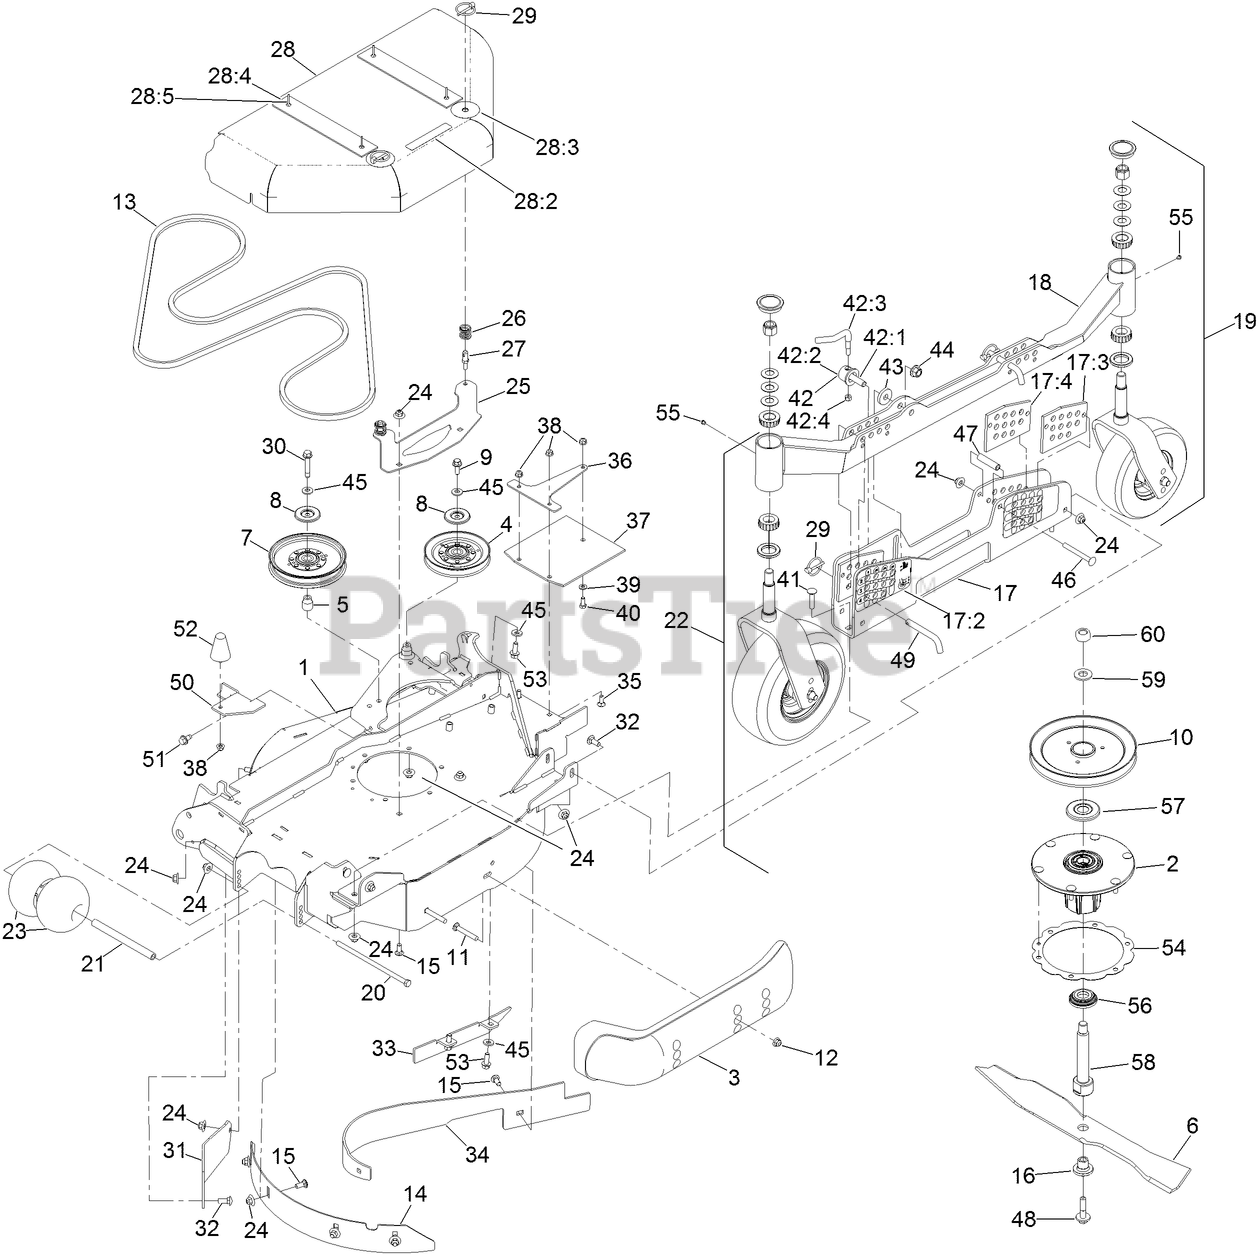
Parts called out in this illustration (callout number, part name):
1	LH WING DECK ASM
2	SPINDLE ASM
3	SKID-BUMPER, DECK
4	IDLER-V
5	BUSHING-IDLER
6	BLADE-24.50 MULCH
7	IDLER-PULLEY
8	SHIELD-DUST
9	SCREW-HHF
10	SHEAVE-DRIVE, BLADE
11	SCREW-CARR
12	NUT-HF, NI
13	BELT-V
14	BAFFLE-DEPTH, LH
15	BOLT-CARR
16	BUSHING-HEX
17	LH HOC CHANNEL ASM
17:2	DECAL-HEIGHT OF CUT-LH
17:3	PLATE-GUIDE, HOC (LH)
17:4	PLATE-GUIDE, HOC (RH)
18	TUBE-HOC, LH
19	REAR CASTER WHEEL ASM
20	SCREW-HH
21	SPACER-WHEEL
22	CASTER WHEEL ASM
23	ROLLER-SCALP, ANTI
24	NUT-FLANGE, NI
25	BRACKET-SHIELD MOUNT, OUTER
26	SPRING
27	PIN, SPRING
28	LH WING SHIELD ASM
28:2	DECAL-NO STEP
28:3	DECAL-SCRATCH COVER
28:5	RIVET-POP
29	PIN-LYNCH
30	SCREW-HHF W/ PATCH
31	PLATE-FILL, LH DECK
32	BOLT-CARR
33	FIN-BAFFLE, DISCHARGE WING (LH)
34	BAFFLE-DOGLEG, CENTER (RH)
35	SCREW-CARR
36	SUPPORT-FLAP, LH
37	GUARD-TIRE, LH
38	NUT-HF, NI
39	WASHER-PLAIN
40	SCREW-HH
41	SCREW-CARR
42	LEVER ASM
42:1	SCREW-LOCK
42:2	CAP-LOCK
42:4	NUT-LOCK, NI
43	WASHER
44	NUT-LOCK
45	WASHER-BELLEVILLE
46	SCREW-CARR
47	SPACER
48	SCREW-SEMS
49	PIN-HOC
50	BRACKET-COVER RETAINER
51	SCREW-HWH
52	BUMPER-RUBBER
53	SCREW-HHF
54	RING-SPACER, HOUSING
56	GUARD-BOTTOM
57	GUARD-BEARING, TOP
58	SHAFT-SPINDLE
59	WASHER
60	NUT-HEX
